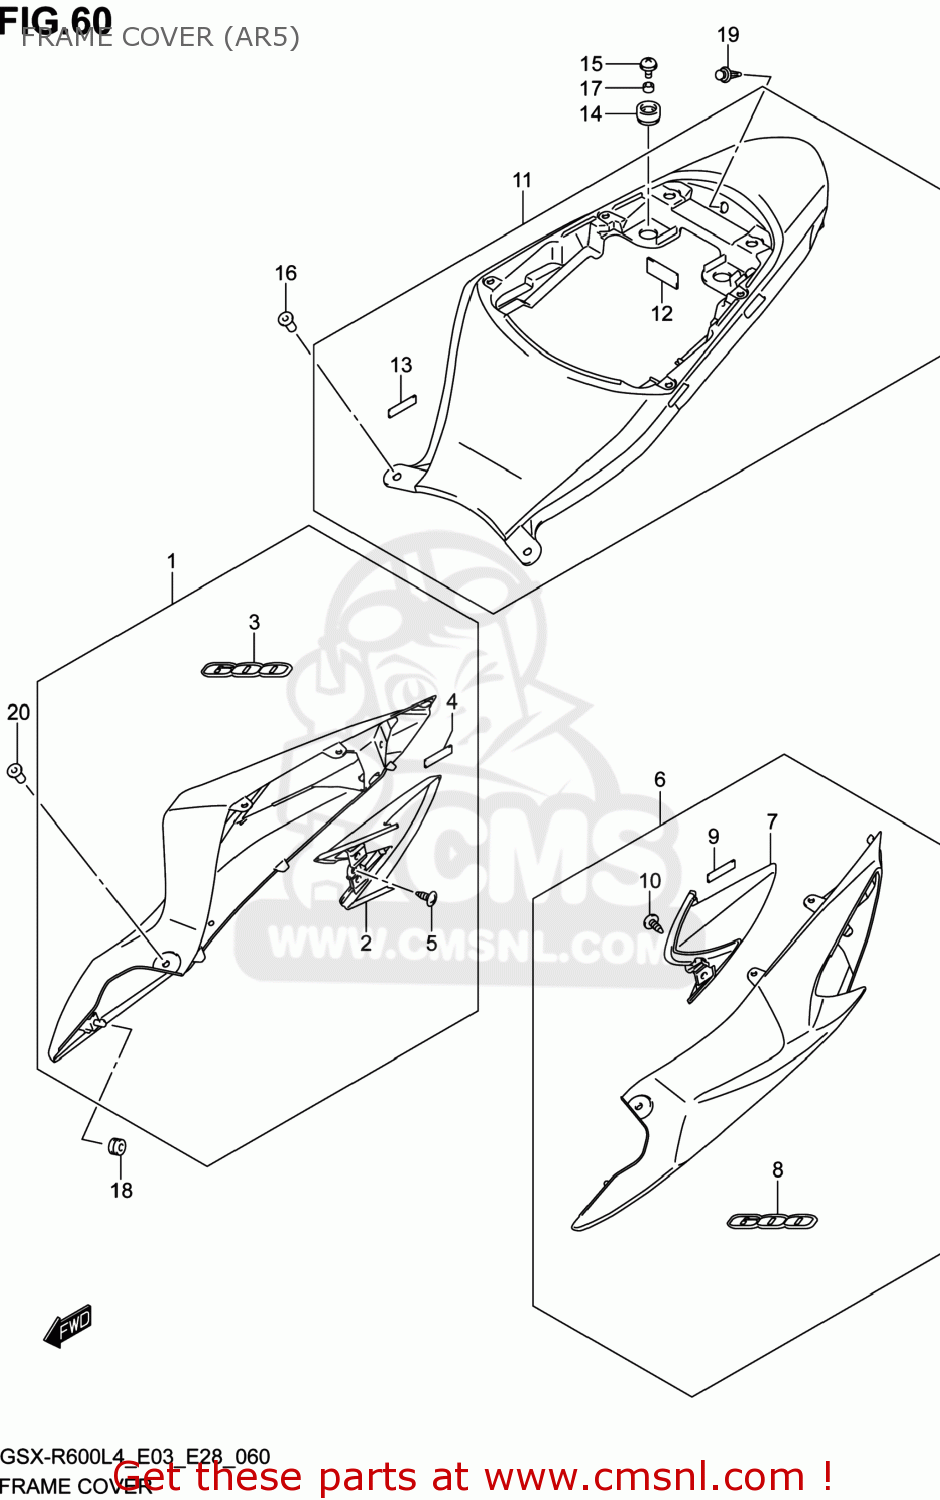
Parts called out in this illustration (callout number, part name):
1	COVER ASSY,FRAME,R
2	COVER,FRAME RR,R
3	EMBLEM,600
4	TAPE(6X25X0.13)
5	SCREW
6	COVER ASSY,FRAME,L
7	COVER,FRAME RR,L
8	EMBLEM,600
9	TAPE(6X25X0.13)
10	SCREW
11	COVER ASSY,FRAME CTR
12	CUSHION
13	TAPE(6X25X0.13)
14	CUSHION,FRAME COVER RR
15	SCREW(6X16)
16	NUT
17	SPACER(6.5X10X7)
18	CUSHION
19	CLIP(BLACK)
20	SCREW
